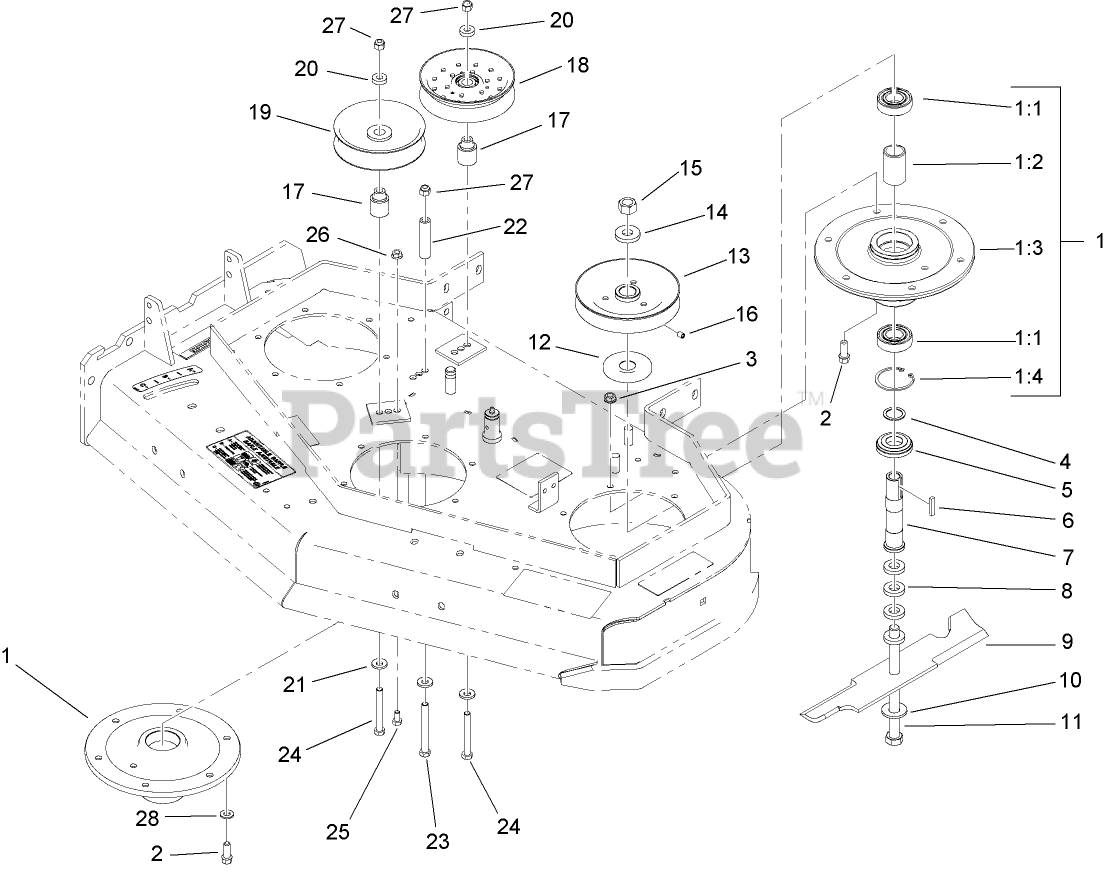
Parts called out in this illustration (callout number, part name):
1	SPINDLE HOUSING ASM
1:1	BEARING
1:2	SPACER-BEARING
1:3	HOUSING-SPINDLE
1:4	RING-SNAP
2	SCREW-HWH
3	NUT-HHF, WHIZ
4	WASHER-SPACER
5	SPACER-GUARD, BOTTOM
7	TUBE-SPINDLE, SHORT
8	SPACER
9	BLADE-14 INCH (HIGH SAIL)
10	WASHER-SPRING
11	SCREW-CAP, HH
12	Guard-Bearing, Top
13	SHEAVE
14	WASHER-RETAINER, SHEAVE
15	NUT-HEX
16	SCREW-SET
17	BUSHING-IDLER
18	IDLER-PULLEY, FLAT
19	PULLEY-IDLER
20	SPACER
21	WASHER-BELLEVILLE
22	SPACER
23	SCREW-HH
24	SCREW-HH
25	SCREW-HH
26	NUT-HF
27	NUT-LOCK, NI
28	WASHER-FLAT
